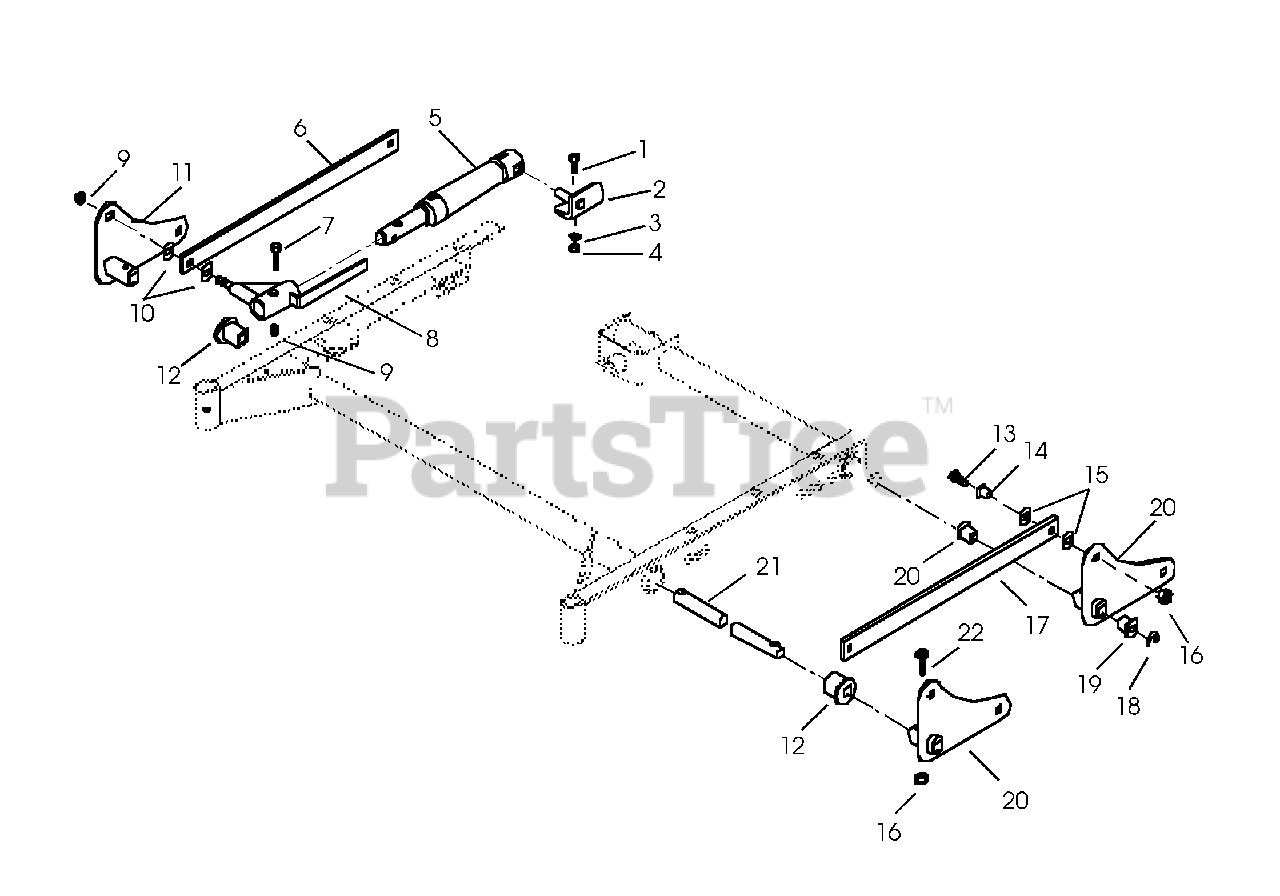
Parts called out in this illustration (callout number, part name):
1	Bolt-Hex .38-16 x 1.50 Grade 5
2	Deck Lift-Rear Deck Bracket-Left Hand
3	Washer-Flat-Steel .438 x 1.0 x .083
4	Nut-Locking-Center .375-16 Grade 2
5	Cylinder-Hydraulic
6	Link Bar-Right Hand Deck Lift
7	Bolt-Hex .50-13 x 2.00 Grade 5
8	Lift Ram-Terminal Pin
9	Nut-Locking-Center .50-13 Grade 5
10	Washer-Hardened-Steel-Thrust .515 x .97 x .062
11	Lift Arm-Weldment
12	Bushing-Flange 1.020 x 1.385 x .75 x 1.75
13	Bolt-Hex .31-18 x 1.25 Grade 5
14	Bushing-Flange .325 x .500 x .513 x .875
15	Washer-Flat-Steel .312 x .734 x .065
16	Nut-Locking-Center .31-18
17	Link Bar-Deck Lift
18	Ring-Retaining-External .750 x .050
19	Bushing-Flange .762 x 1.0 x .580 x 1.48
20	Lift Arm-Weldment-Left Hand
21	X-Shaft 50 Deck Lift
22	Bolt-Hex .31-18 x 1.75 Grade 5
